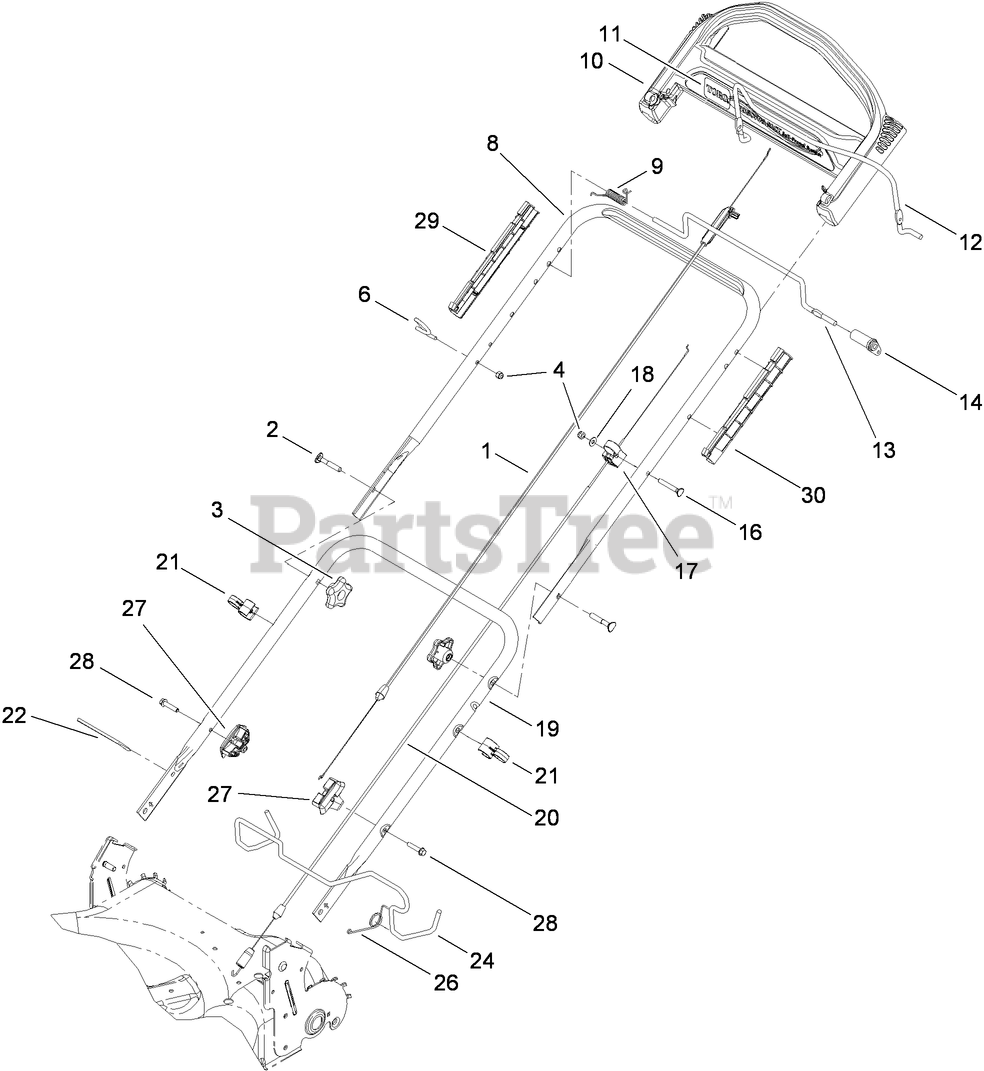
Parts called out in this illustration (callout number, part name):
1	CABLE-BRAKE
2	SCREW-HANDLE
3	KNOB-LOCKING
4	NUT-LOCK, NI
6	GUIDE-ROPE
8	Handle-Upper
9	Spring-Torsion
10	HANDLE-CONTROL
11	DECAL-HANDLE
12	Bail-Brake
13	BAR-CONTROL, TRACTION
14	LEVER-TRACTION
16	SCREW
17	ANCHOR-CABLE
18	WASHER-FLAT
19	HANDLE-LOWER
20	Cable-Traction
21	Guide-Cable
22	TIE-CABLE
24	RELEASE LEVER ASM
26	SPRING-TORSION
27	ANCHOR-BAG
28	SCREW-HWH
29	GUIDE-RH
30	GUIDE-LH
